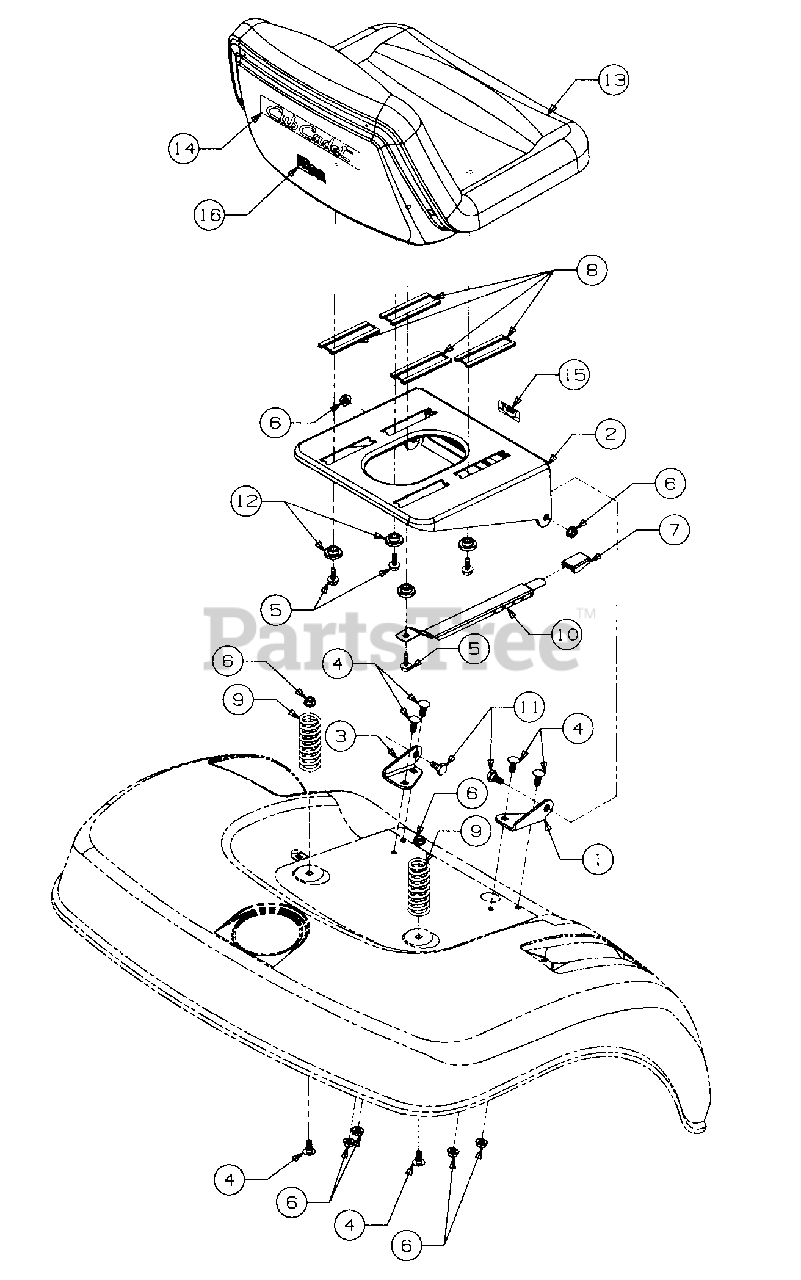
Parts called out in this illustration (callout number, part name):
5	Screw, Hex Wash Sf-Tapp 5/16-18 X.75 Lg
6	Nut, Hex Flange Top Lock 5/16-18 8
7	Knob, Seat Adjuster
8	Slide, Seat
9	Spring, Compression 1.9 OD X 2.4 Lg
10	Adjuster, Seat
11	Bolt, Shoulder
12	Spacer, Shoulder
13	Seat, Medium Back
14	Graphic, Seat Back Script
15	Graphic, Seat Adjuster
16	Graphic, Made in USA
